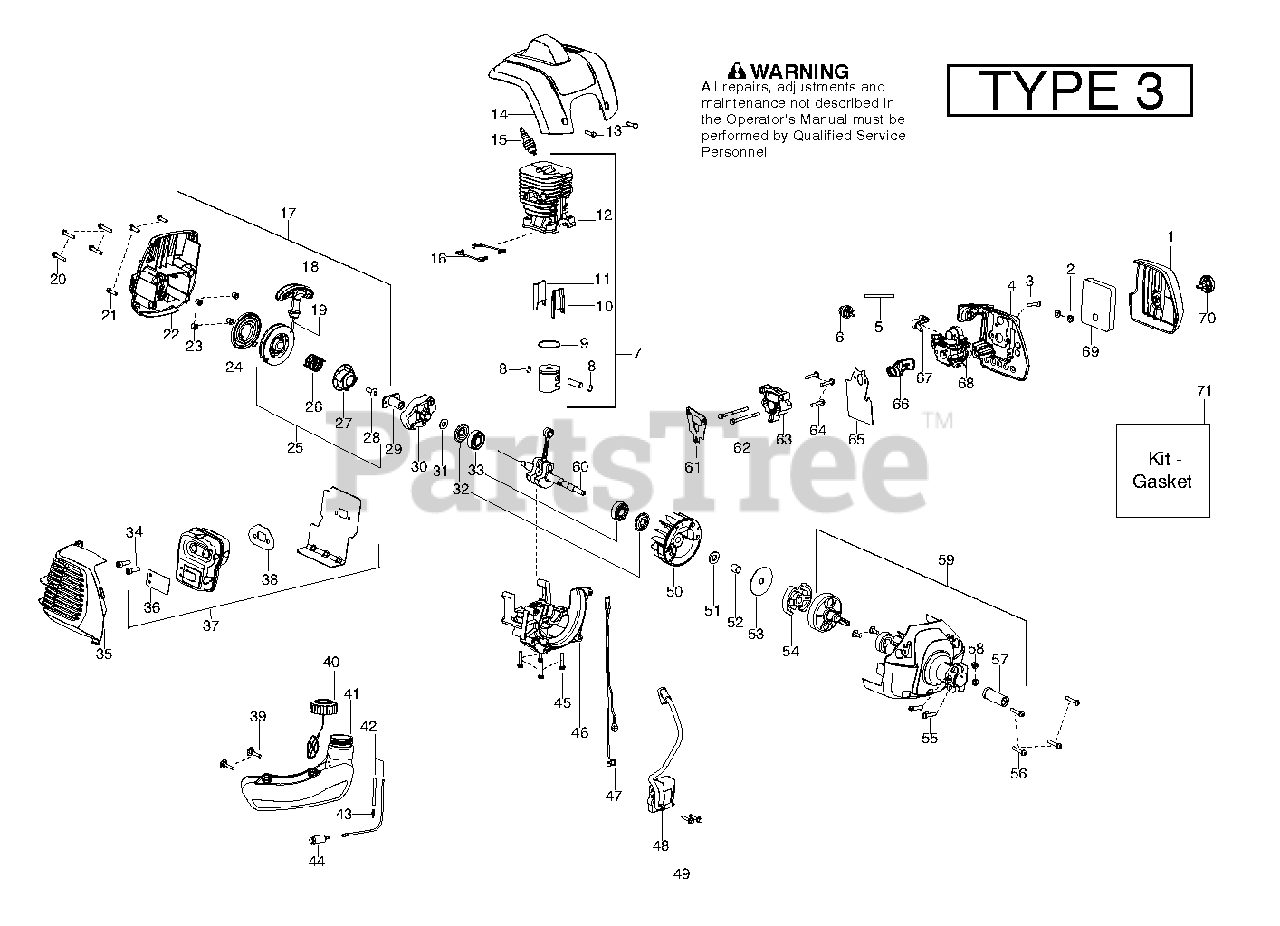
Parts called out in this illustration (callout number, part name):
4	BASE AIRBOX BLACK
7	KIT
8	RETAINER PISTON PIN
10	INSERT FRONT TRANSFER PORT
12	CYLINDER CHROME 33CC
13	SCREW M4 X 1.75 PT 16MM
14	CYLINDER COVER
15	PLUG-SPARK (RCJ-6Y)
16	GASKET KIT 33CC
18	STARTER HANDLE
20	B0LT, C/SHAFT 36/41
21	SCREW M4 X 1.75 PT 16MM
22	STARTER HOUSING
24	SPRING STARTER
25	KIT STARTER PULLEY
29	SLEEVE COUPLING
30	STARTER CUP ASSY
32	GASKET KIT 33CC
33	BEARING RADIAL BALL (6201)
35	MUFFLER COVER
36	SPARK ARRESTER
38	GASKET KIT 33CC
39	SCREW FUEL TANK RETAINER
40	ASSY FUEL CAP W/RETAINER
41	ASSY FUEL TANK W/RETAINER
42	KIT-LINE(FUEL)
43	FUEL LINE FITTING
44	FUEL PICK-UP ASSY
45	B0LT, C/SHAFT 36/41
48	IGNITION MODULE
50	FLYWHEEL ASSY
51	WASHER CLUTCH
52	SPACER FLYWHEEL
53	WASHER-CLUTCH
54	CLUTCH ASSY
55	SCREW-10-24 X 1" (UNC)
56	B0LT, C/SHAFT 36/41
57	GUIDE CLUTCH DRUM/FLEXSHAFT
58	LOCKNUT-HEX 10-24
59	CLUTCH COVER ASSY
60	CRANKSHAFT
61	GASKET KIT 33CC
63	ADAPTER, CARBURETOR
65	GASKET KIT 33CC
66	CARB BOOT ADAPTER
67	Choke Control Lever
68	CARBURETOR
70	AIRBOX KNOB ASSY BLACK
71	GASKET KIT 33CC
